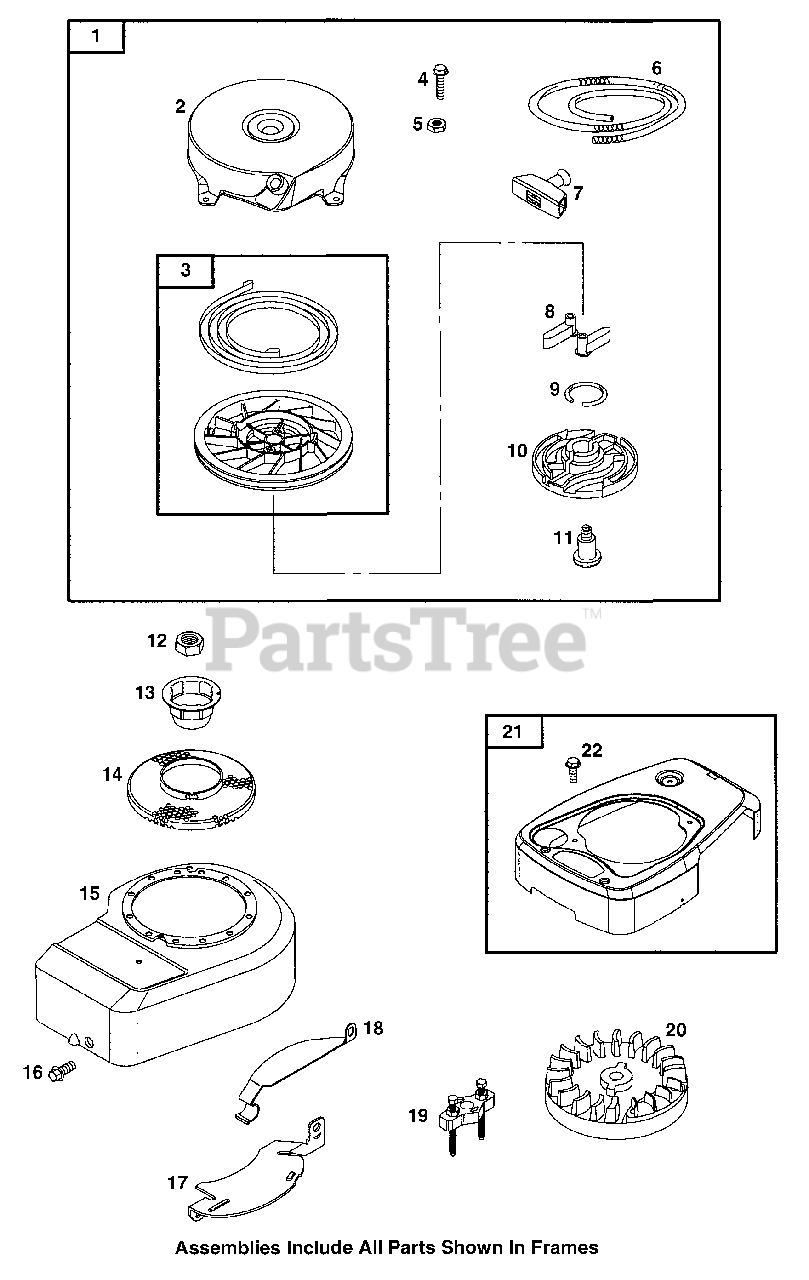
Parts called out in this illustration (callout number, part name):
1	Starter-Rewind
2	Housing-Rewind Starter
3	Assembly-Pulley Spring
4	Hex Screw
5	Hex Nut
6	Starter Rope
7	Starter Rope Grip
8	Pawl-Rachet
9	Spring-Friction
10	Plate-Pawl Friction
11	Shoulder Screw
12	Flywheel Nut
13	Flywheel Cup
14	Rotating Screen
15	Blower Housing
16	Hex Screw
17	Flywheel Guard
19	Flywheel Puller
21	Blower Housing Cover
22	Hex Screw
